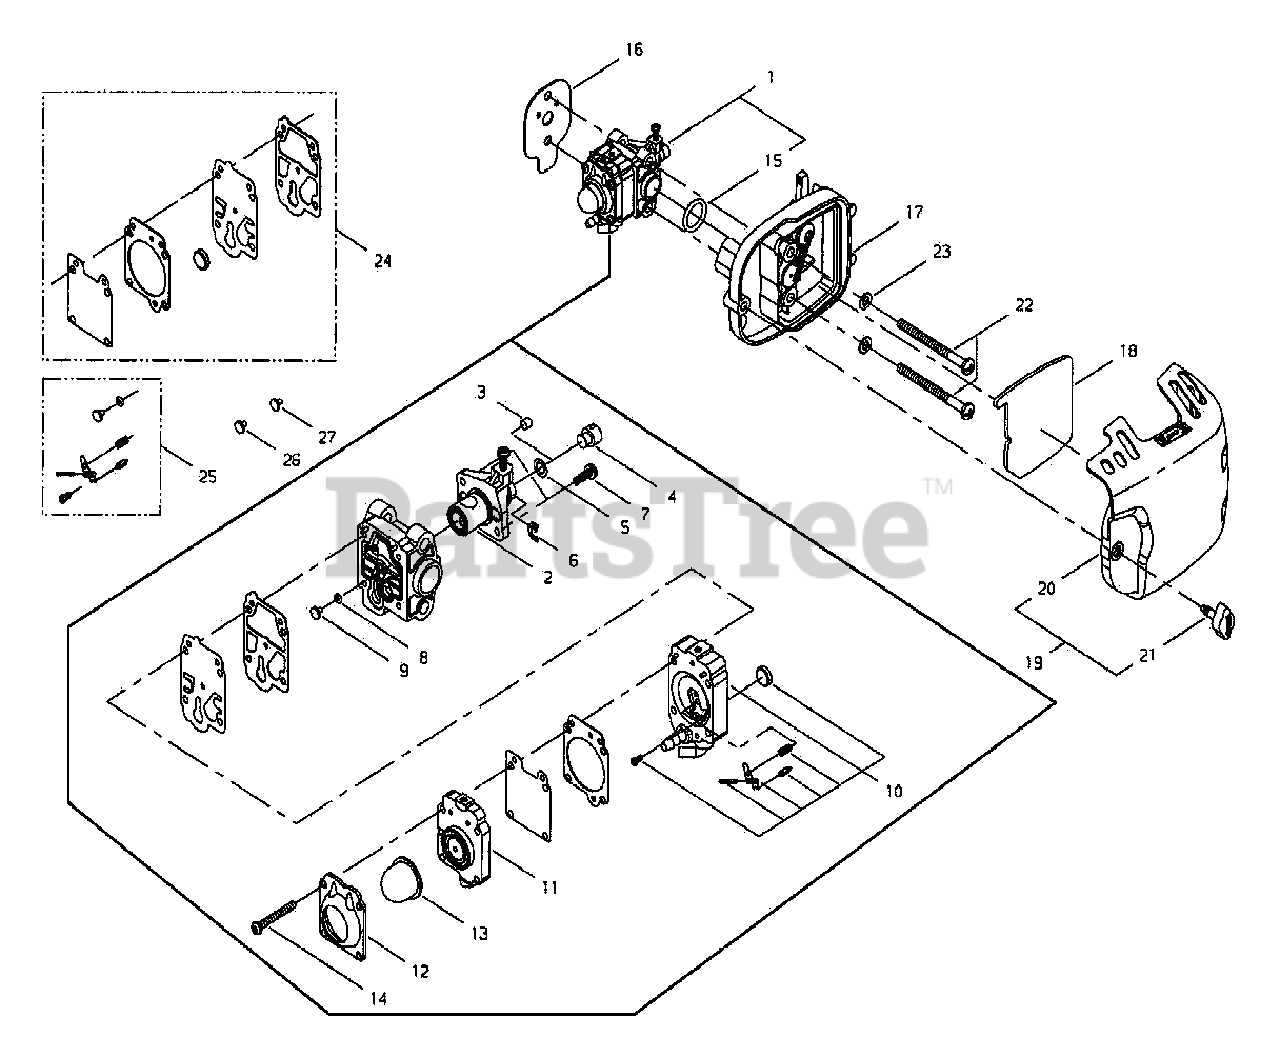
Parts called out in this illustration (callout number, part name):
1	CARBURETOR
2	VALVE ASSY, THROTTLE
3	PLUG
4	SWIVEL
5	WASHER
6	E-RING
7	SCREW, THROTTLE COLLAR
8	O-RING
9	JET, MAIN
10	BODY ASSY, PUMP
11	BODY ASSY, PURGE
12	RETAINER, PURGE BULB
13	BULB, PURGE
14	SCREW
15	O-RING 15
16	GASKET, INTAKE
17	CASE ASSY, AIR FILTER
18	FILTER, AIR
19	COVER ASSY, AIR FILTER
20	COVER, AIR FILTER
21	THUMBSCREW M5
22	SCREW M5×60
23	WASHER 5 MM
24	GASKET / DIAPHRAGM KIT
25	VALVE KIT, INLET NEEDLE
26	JET, MAIN
27	JET, MAIN
